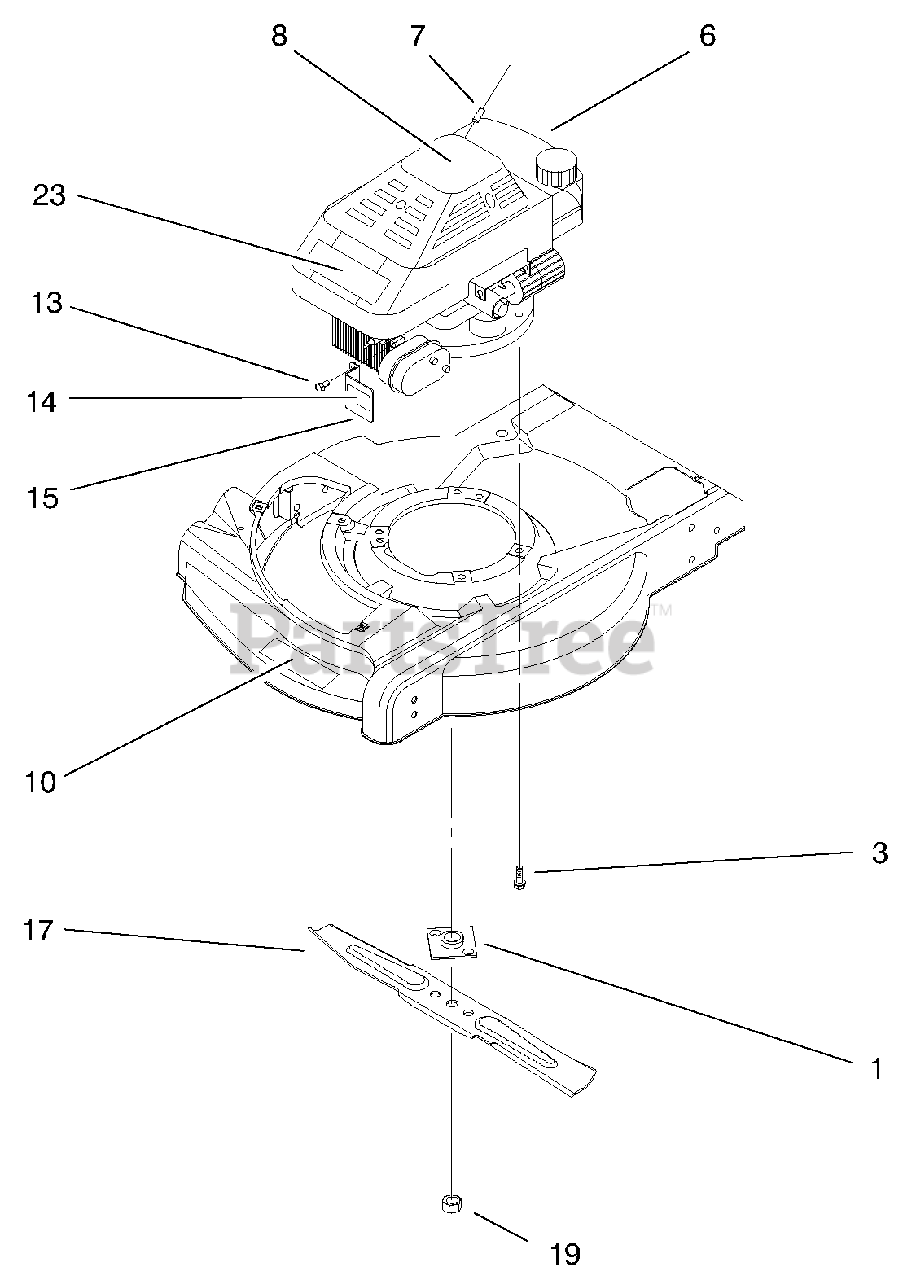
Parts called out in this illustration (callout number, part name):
1	ASM-Plate & Collar
3	Screw-Engine Mount
6	ASM-Engine
7	Rope-Stop
8	Decal-Shroud Top
10	Decal-Deck
14	Decal-Hot Surface
15	Guard-Muffler
17	Blade-21" Whirl
19	Nut-Blade
23	Applique
